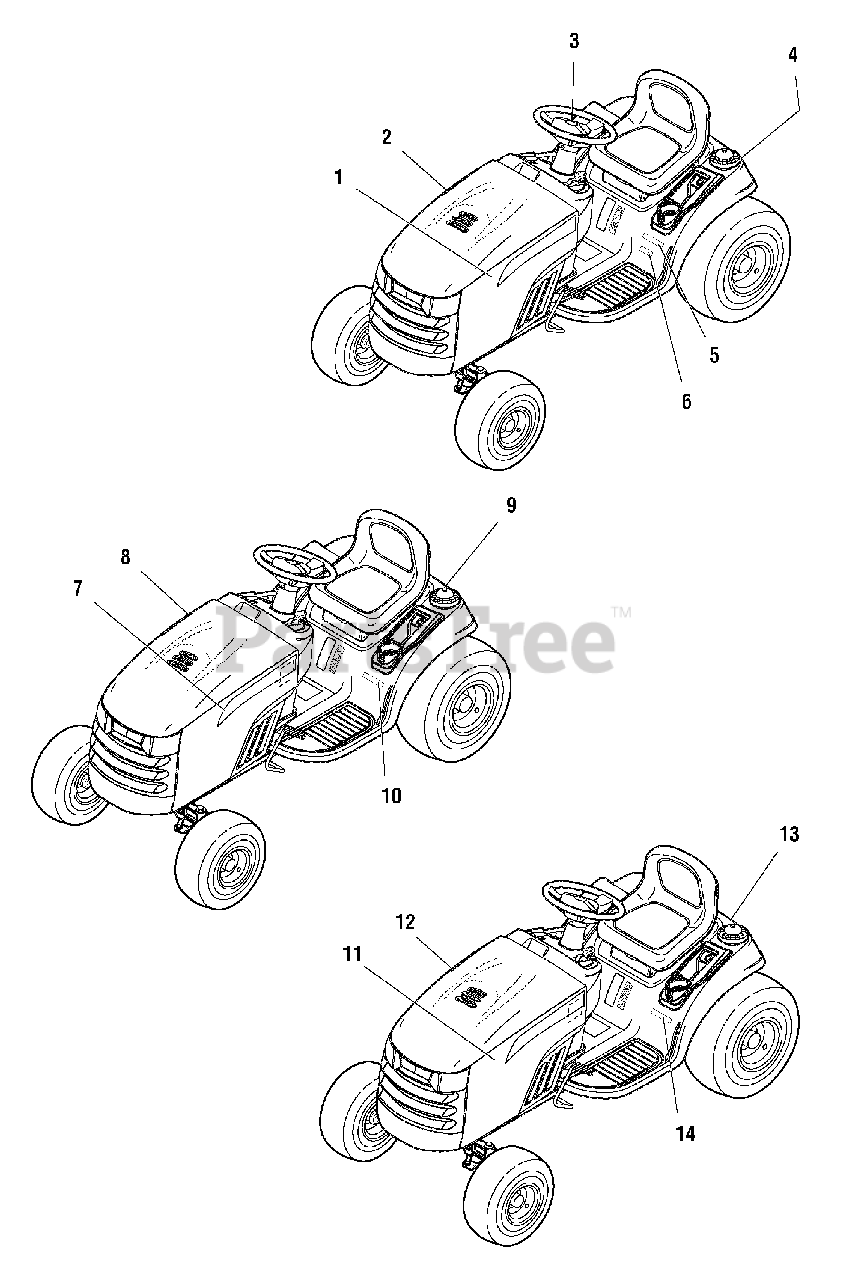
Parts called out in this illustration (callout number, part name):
1	DECAL, Simplicity, LH Stripe
2	DECAL, Simplicity, RH Stripe
3	DECAL, SMI Steering Wheel Icon Orange
4	DECAL, Simplicity
5	DECAL, Regent, Silver & Blue
6	DECAL, 18HP, Silver/Clear
6	DECAL, 18.5HP, Silver/Clear
6	DECAL, 19.5HP, Silver/Clear
6	DECAL, 20HP, Silver/Clear
6	DECAL, 22HP, Silver/Clear
6	DECAL, 24HP, Silver/Clear
7	DECAL, AGCO, LH Hood Stripe
8	DECAL, AGCO, RH Hood Stripe
9	DECAL, AGCO Logo
10	DECAL, 518 White/Clear
10	DECAL, 520 White/Clear
10	DECAL, 522 White/Clear
10	DECAL, 524 White/Clear
11	DECAL, Massey, LH Hood Stripe
12	DECAL, Massey, RH Hood Stripe
13	DECAL, Massey Ferguson
14	DECAL, 2518, Gray/Clear
14	DECAL, 2520, Gray/Clear
14	DECAL, 2522, Gray/Clear
14	DECAL, 2524, Gray/Clear
14	DECAL, 25195, Gray/Clear
14	DECAL, 2500, 21-38, Gray/Clear
14	DECAL, 2000, 20-42, Gray/Clear
14	DECAL, 2000, 21-42, Gray/Clear
